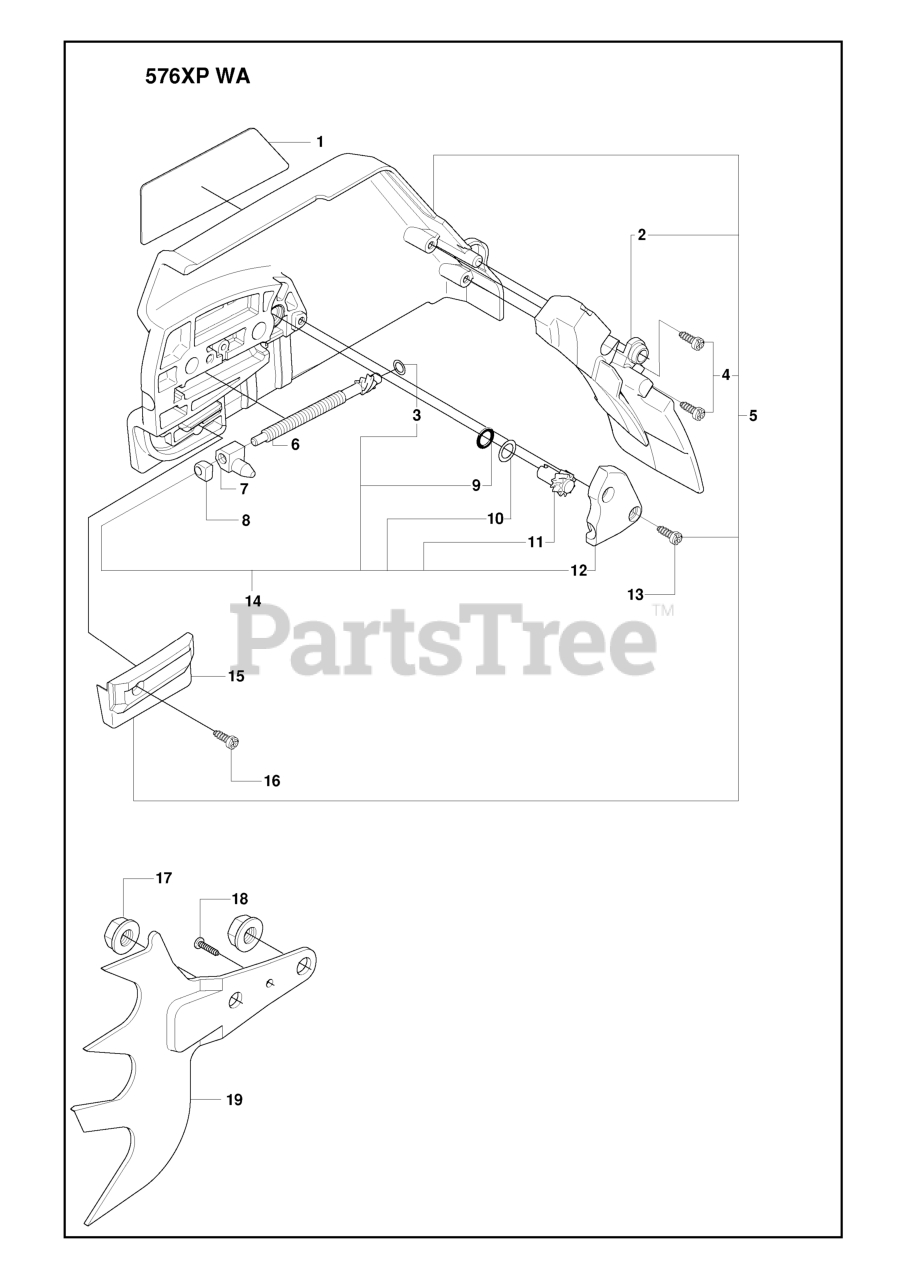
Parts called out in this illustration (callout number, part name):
5	CLUTCH COVER ASSY
6	ADJUSTER
11	RP ADJUSTER
14	KIT-CHAIN TENSIONER
15	CHAIN GUIDE
17	NUT M8 FLANGE
19	FELLING DOG
